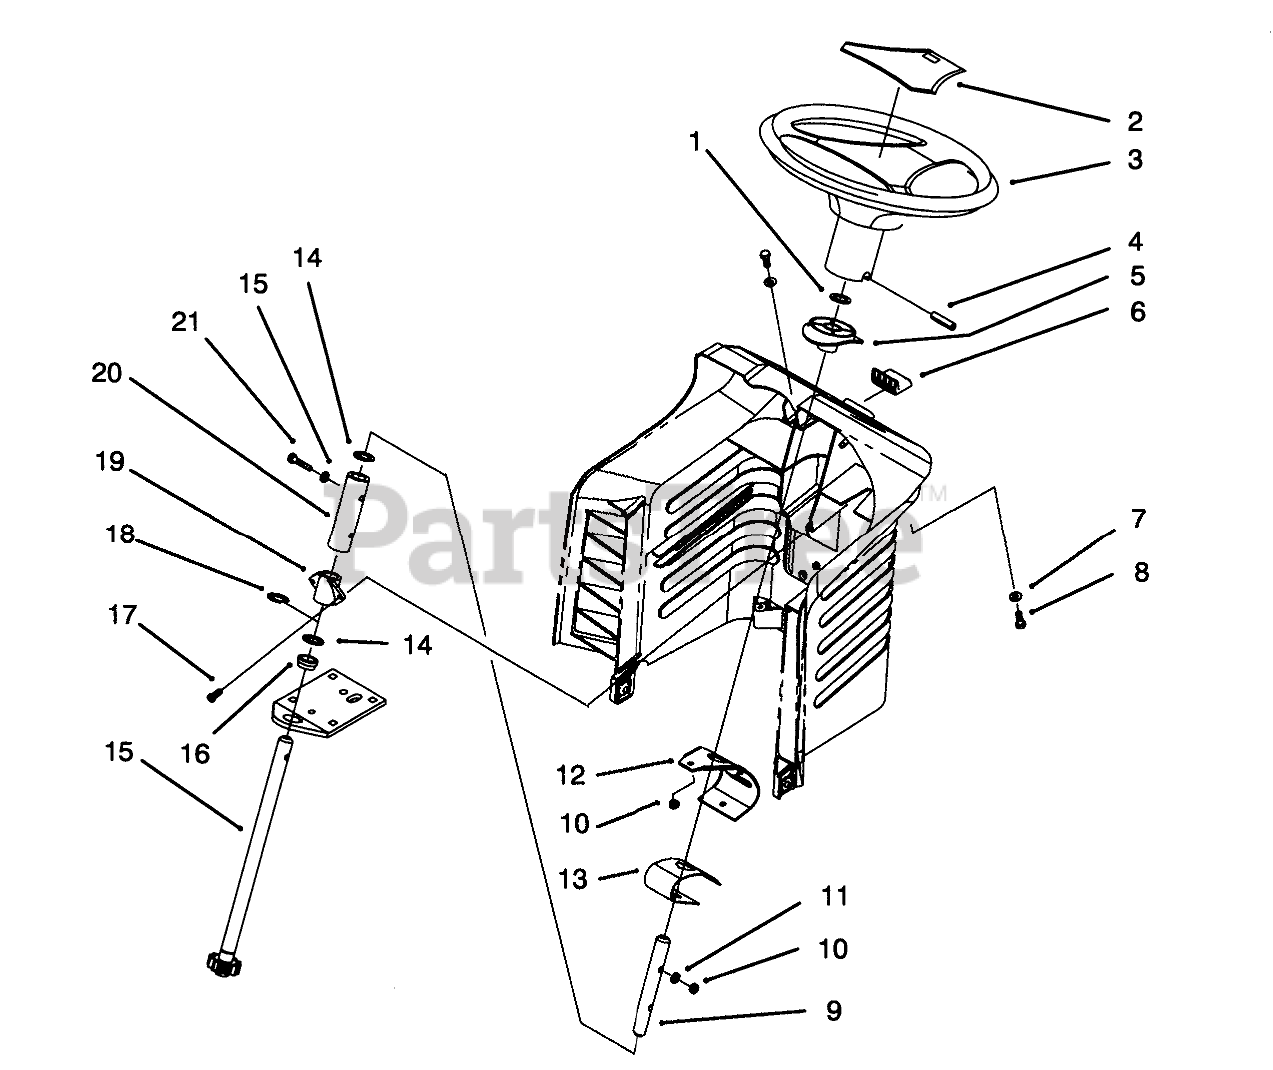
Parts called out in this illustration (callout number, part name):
1	PUSH-ON RETAINING RING
2	COVER-WHEEL
3	Wheel-Steering (Incl. Ref. #2)
4	PIN-ROLL
5	BUSHING-SLIDING
6	RELEASE BUTTON
7	WASHER-FLAT
8	SCREW-HH
9	UPPER STEERING SHAFT
10	NUT-LOCK, NI
11	WASHER
12	BACKUP BRACKET
13	SPRING LEAF
14	WASHER-THRUST
15	SHORT STRG SHAFT WA
16	BEARING-FLANGE
17	SCREW-SPECIAL
18	E-RING
19	BUSHING STATIONARY
20	COUPLING, STEERING
21	SCREW-HH
